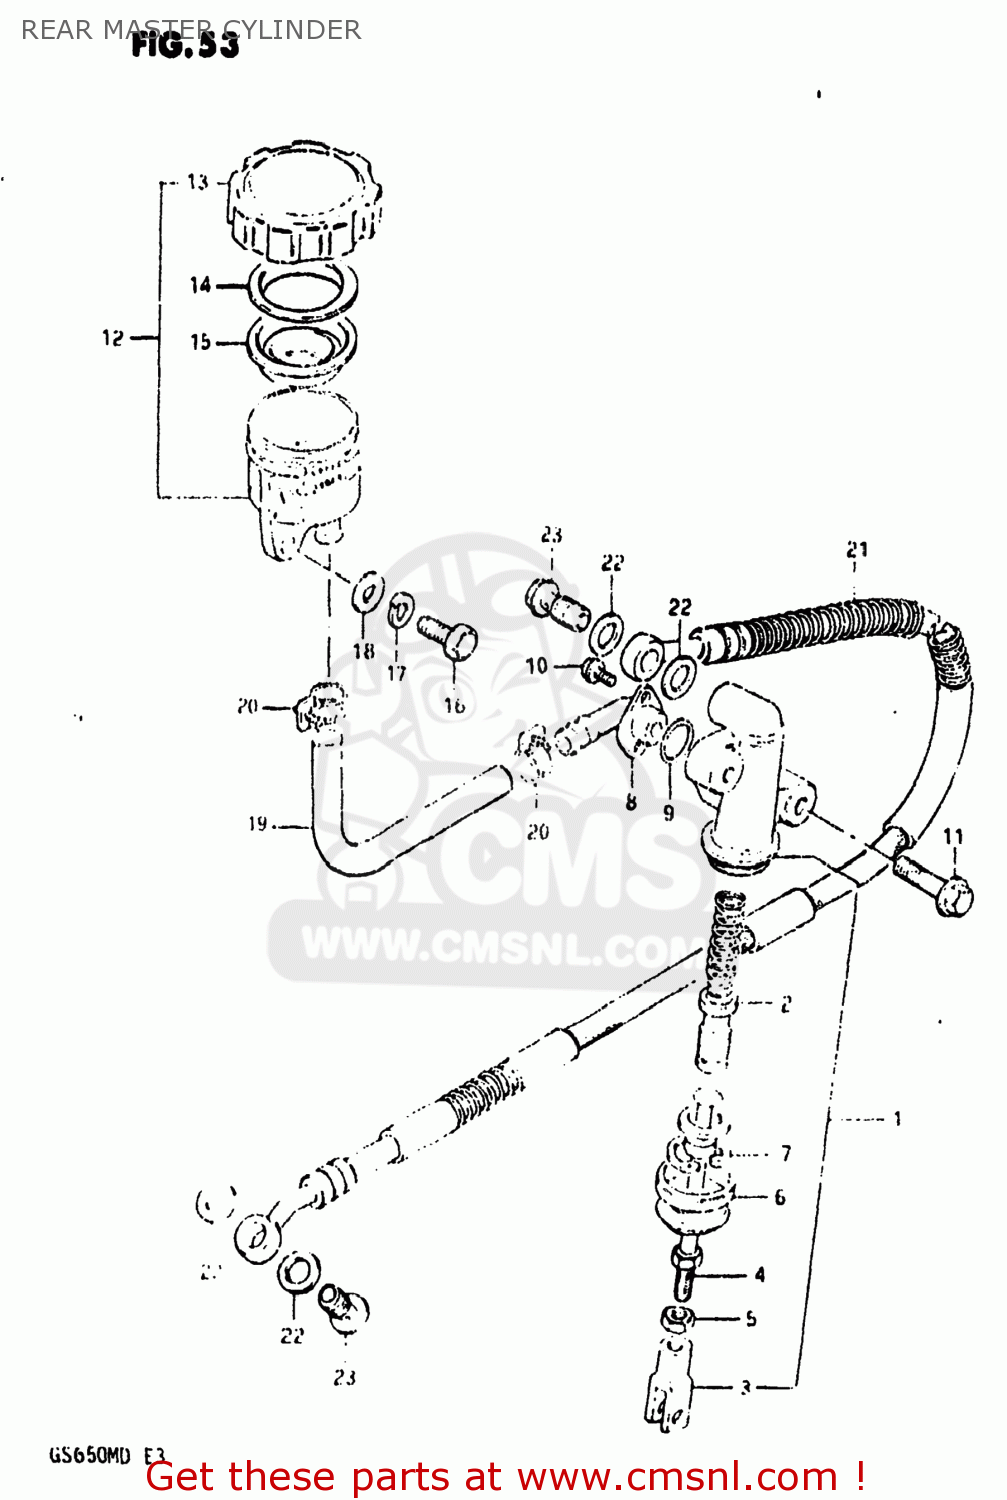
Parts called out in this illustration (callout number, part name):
1	CYLINDER ASSEMBLY,REAR MASTER
2	PISTON/CUP SET
3	YOKE
4	ROD,REAR MASTER CYLINDER
5	NUT,MASTER CYLINDER
6	BOOT
7	CIRCLIP
8	CONNECTOR
9	O RING
10	SCREW
11	BOLT
12	TANK ASSEMBLY,RESERVOIR
13	CAP
14	PLATE,DIAPHRAGM
15	DIAPHRAGM
16	BOLT, UPPER
17	LOCK WASHER
18	WASHER
19	HOSE,RESERVOIR TANK
20	CLAMP
21	HOSE,REAR BRAKE
22	WASHER
23	BOLT UNION
